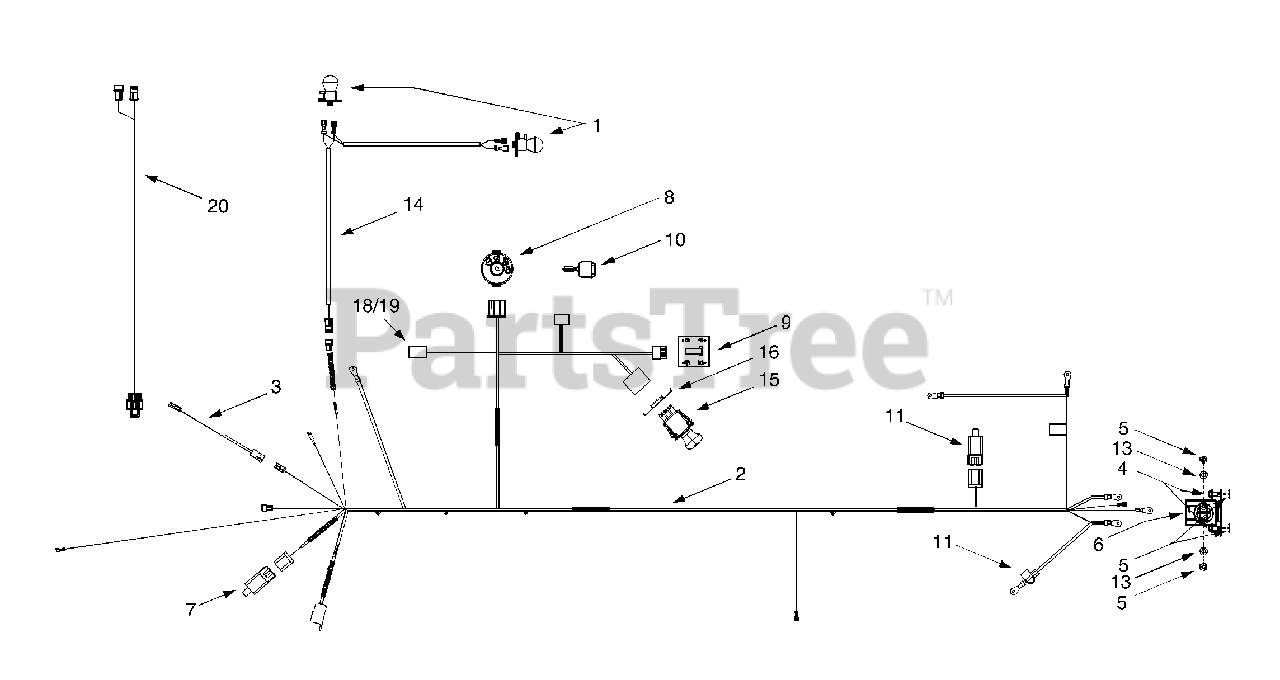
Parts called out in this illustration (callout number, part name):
1	Bulb/Socket Headlight Assembly
2	Wiring Harness w/o Ref. 14
3	Harness Adapter, #18 x 5
4	Self Tapping Screw, 1/4-20 x .5
5	Hex Nut, 1/4-20
6	Solenoid, 12-volt, 100 Amp
7	Snap Mount Safety Interlock Switch
8	Ignition Switch
9	Indicator Monitor / Hour Meter
10	Ignition Key
11	Safety Plunger Switch
13	Lock Washer, 1/4
14	Headlight Harness
15	Electric PTO Switch
16	Retainer Bracket
18	Fuse Holder
19	20-amp Fuse
20	Harness Adapter
